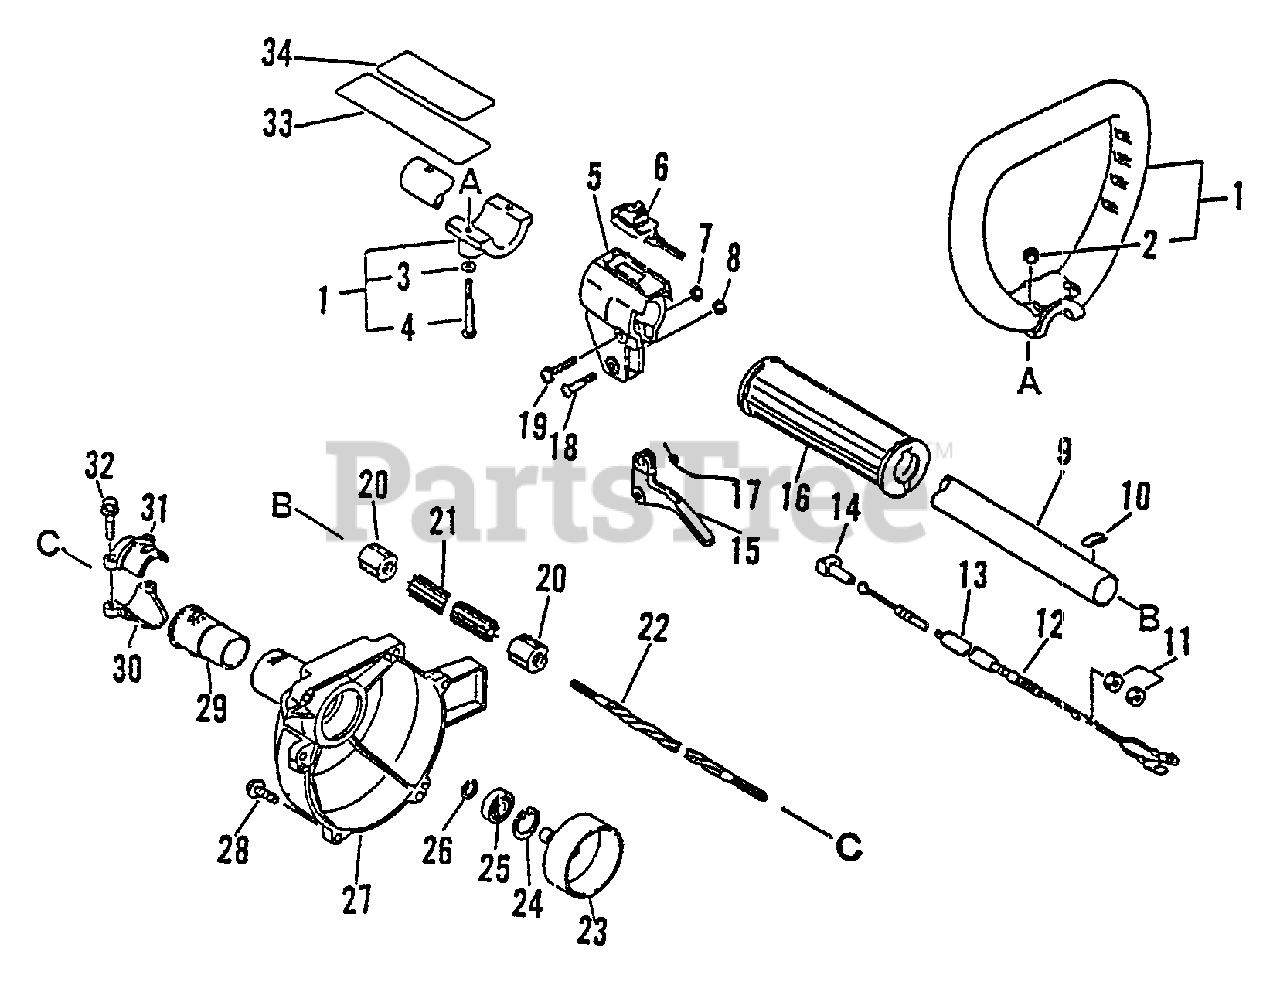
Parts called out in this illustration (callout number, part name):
1	LOOP HANDLE ASSY
2	NUT M5
3	WASHER, FLAT 5.5×10×0.8
4	SCREW 5×40
5	BRACKET, THROTTLE CONTROL
6	IGNITION SWITCH ASSY
7	NUT M5
8	NUT, LOCK M5
9	MAIN PIPE ASSY 25×1500
10	LABEL - ALIGNMENT
12	CABLE, THROTTLE
14	GUIDE, CABLE
15	TRIGGER, THROTTLE
16	GRIP
17	SPRING, THROTTLE
19	SCREW 5×30
21	LINER, FLEXIBLE 21.6×1420
22	DRIVESHAFT - FLEXIBLE
23	DRUM, CLUTCH
24	RING, SNAP 28
25	BEARING, BALL 6201-ZZ
26	RING, RETAINING - 12
27	CASE, FAN
28	SCREW 4×16
31	HOLDER, MAIN PIPE - UPPER
32	BOLT - 5×25
33	LABEL - CAUTION
34	LABEL, CAUTION
